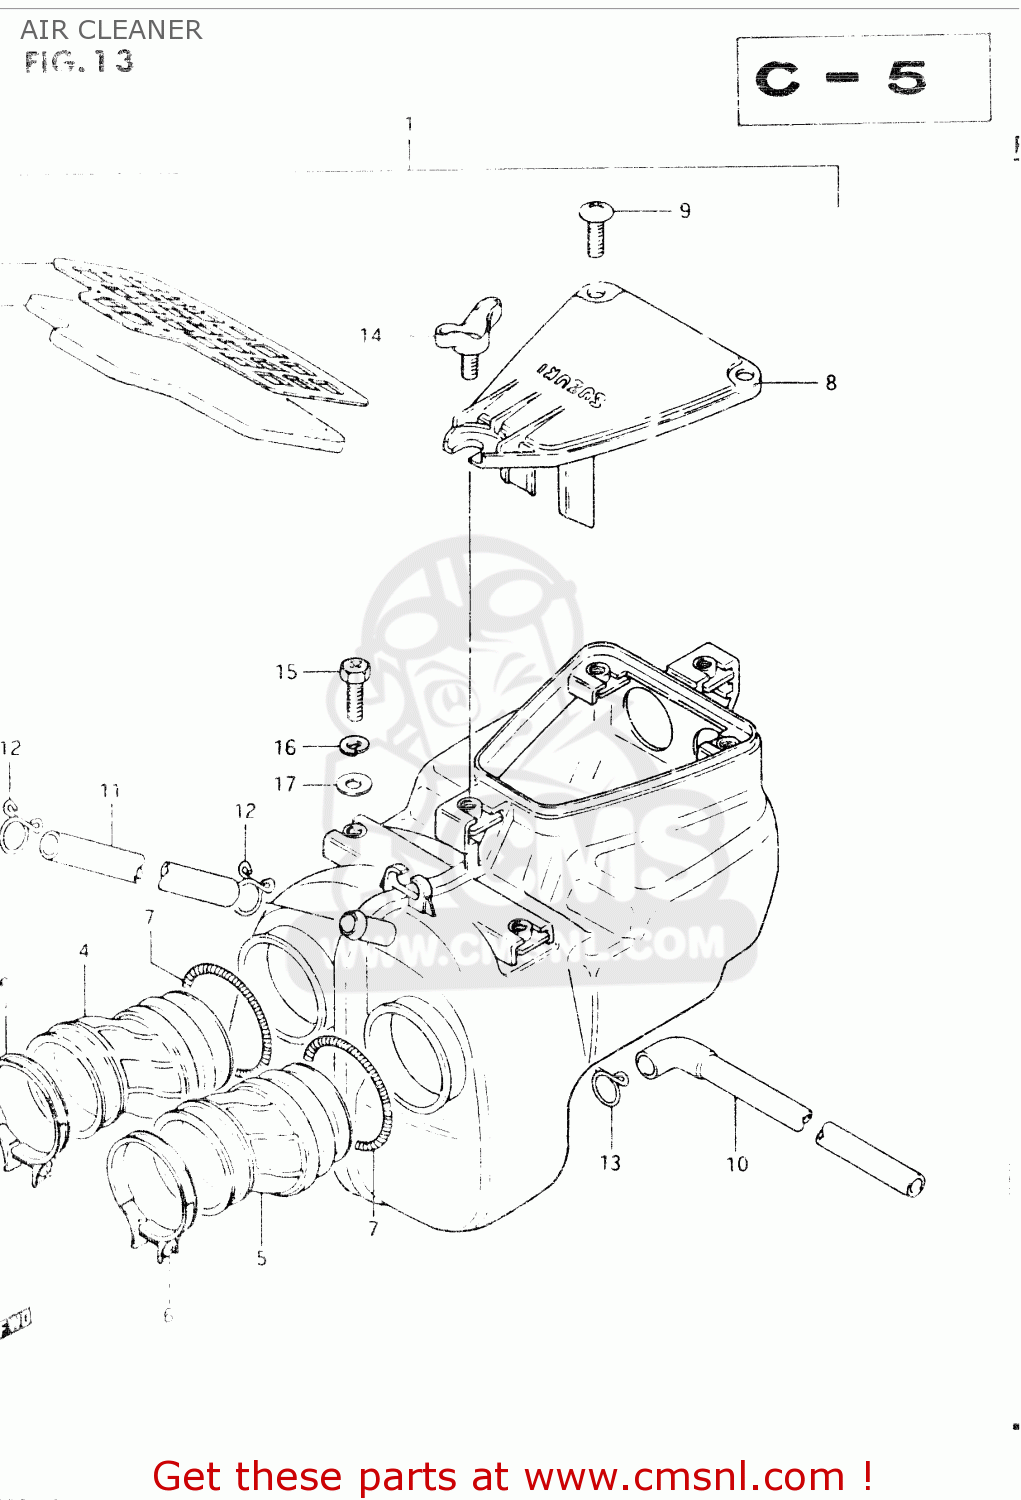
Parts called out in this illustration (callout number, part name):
1	CLEANER ASSEMBLY,AIR
2	FILTER
3	HOLDER,OUTER
4	TUBE,OUTLET,R
5	TUBE,OUTLET,L
6	CLAMP
7	CLAMP,CLEANER SIDE
8	CAP,AIR CLEANER
9	SCREW
10	DRAIN TUBE
11	TUBE,BREATHER
12	CLAMP
13	CLIP
14	BOLT, WING
15	SCREW(6X12)
16	LOCK WASHER
17	WASHER
